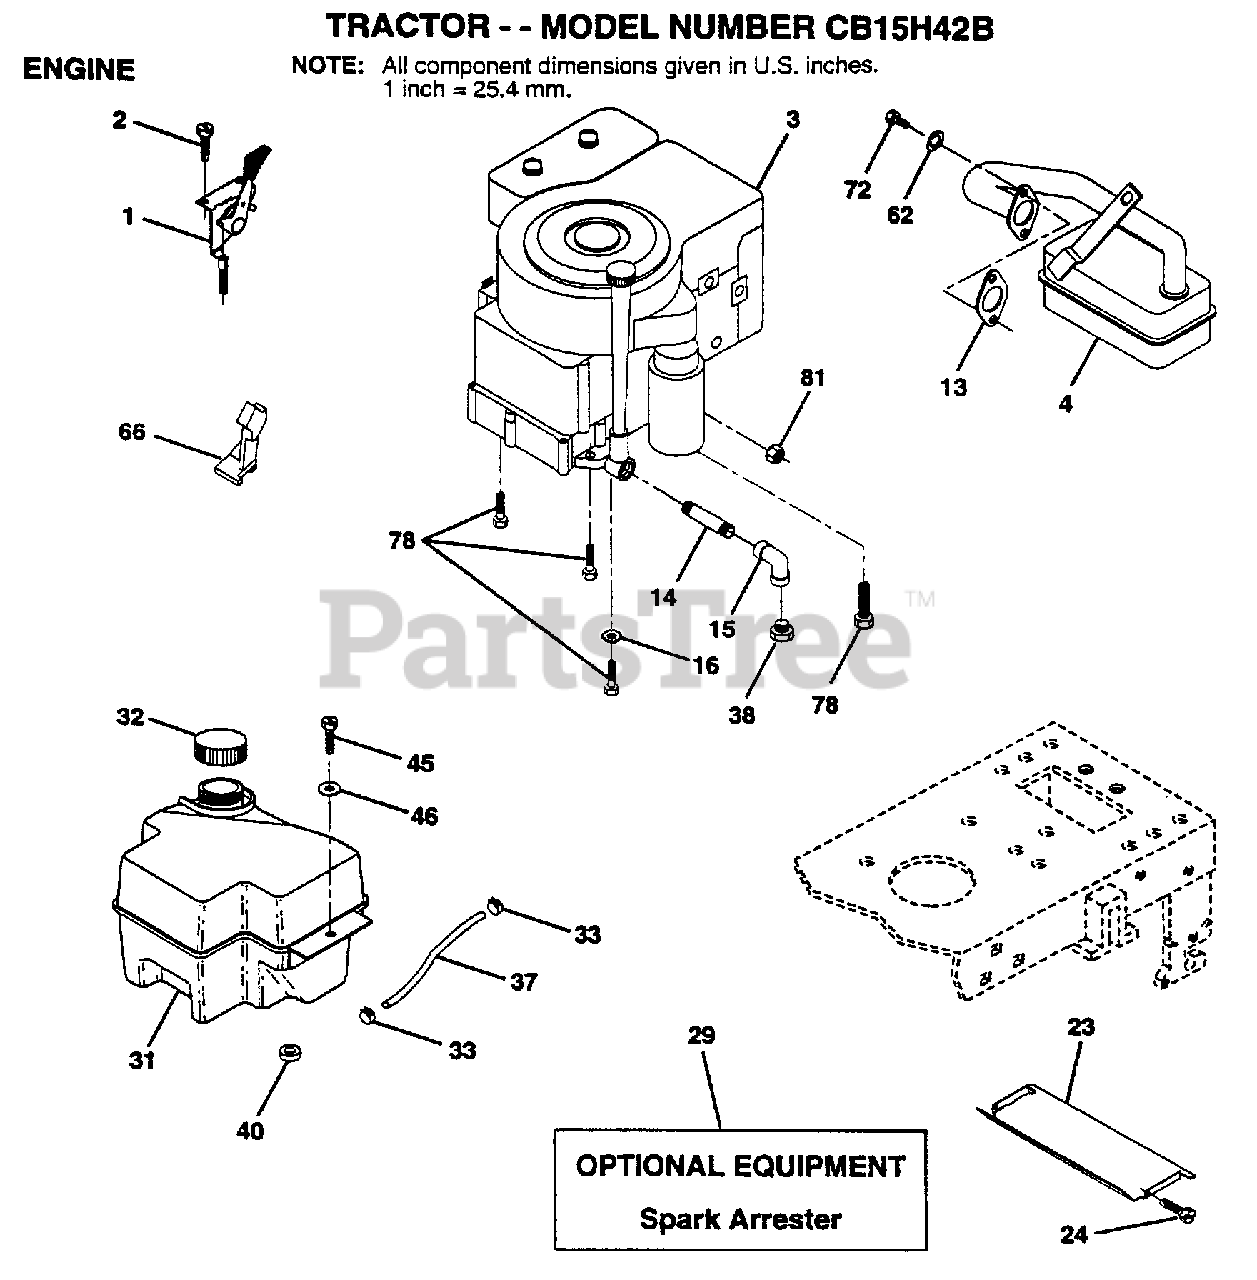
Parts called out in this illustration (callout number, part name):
1	CONTROL.THTL.23.5
2	SCREW LT
4	MUFFLER
14	PIPE NIPPLE
15	ELBOW
16	LOCKWASHER
24	SCREW
31	TANK.FUEL.LT.
32	CAP ASM FUEL
33	HOSE CLAMP
37	LINE FUEL
45	SCREW HEX CRT
46	WASHER
62	LOCKWASHER
66	"STOP,DASH THROTT"
72	SCREW
78	SCREW
81	NUT
